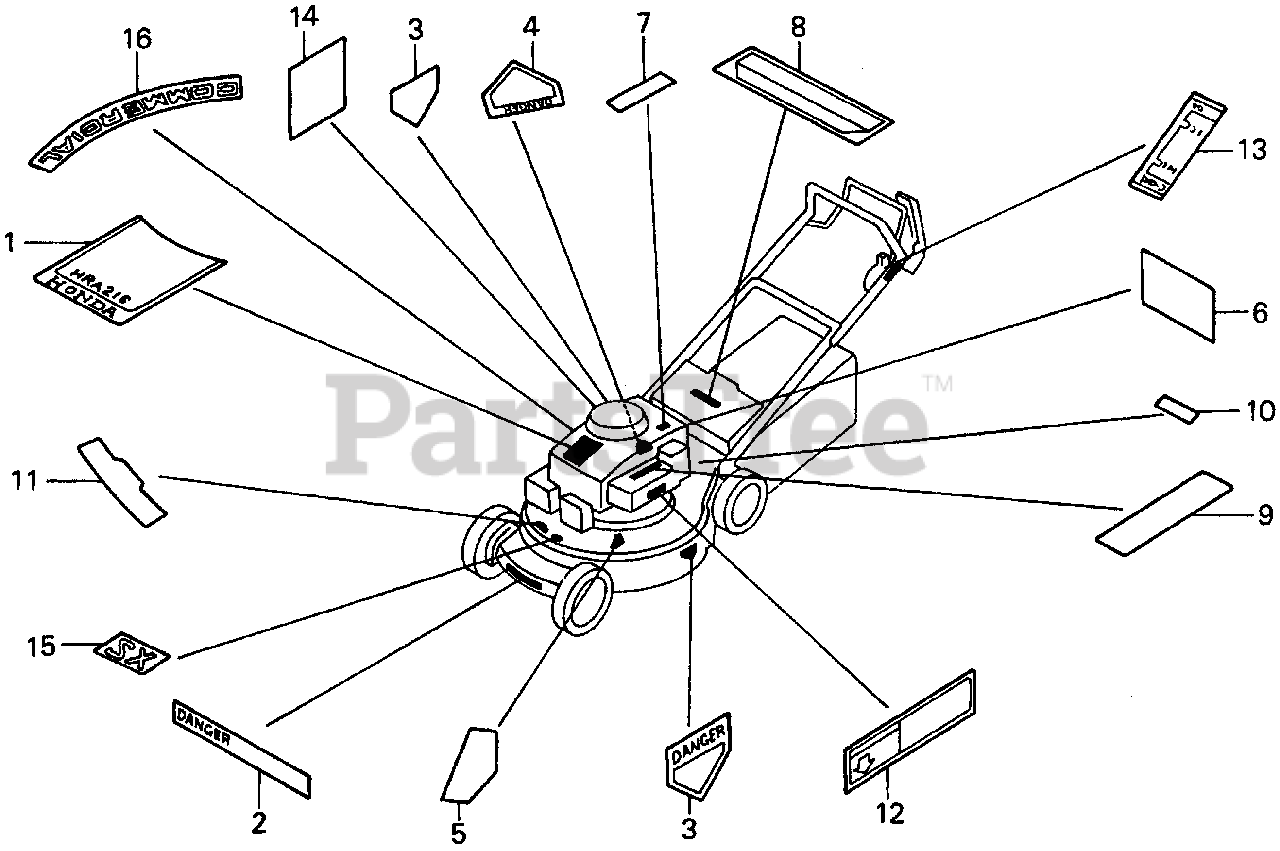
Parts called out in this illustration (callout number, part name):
1	EMBLEM, TOP
2	LABEL A, HOUSING CAUTION (ENGLISH)
3	CAUTION B, HOUSING
3	LABEL C, HOUSING CAUTION
4	LABEL B, HOUSING CAUTION
4	LABEL C, HOUSING CAUTION
5	LABEL, STEP POSITION (ENGLISH)
6	CAUTION, OPERATOR (ENGLISH)
6	CAUTION, OPERATOR (ENGLISH) (NOT AVAILABLE)
7	LABEL, FUEL CAUTION (ENGLISH)
8	LABEL, DISCHARGE GUARD CAUTION (ENGLISH) (NOT AVAILABLE)
9	MARK, EASY START (ENGLISH)
10	LABEL, CHANGE INDICATION
11	LABEL, PLUG CAUTION
12	LABEL, AIR CLEANER CAUTION (H)
13	MARK, THROTTLE (ENGLISH)
14	MARK, OIL CAUTION
15	MARK, TYPE (SX)
16	MARK, COMMERCIAL
